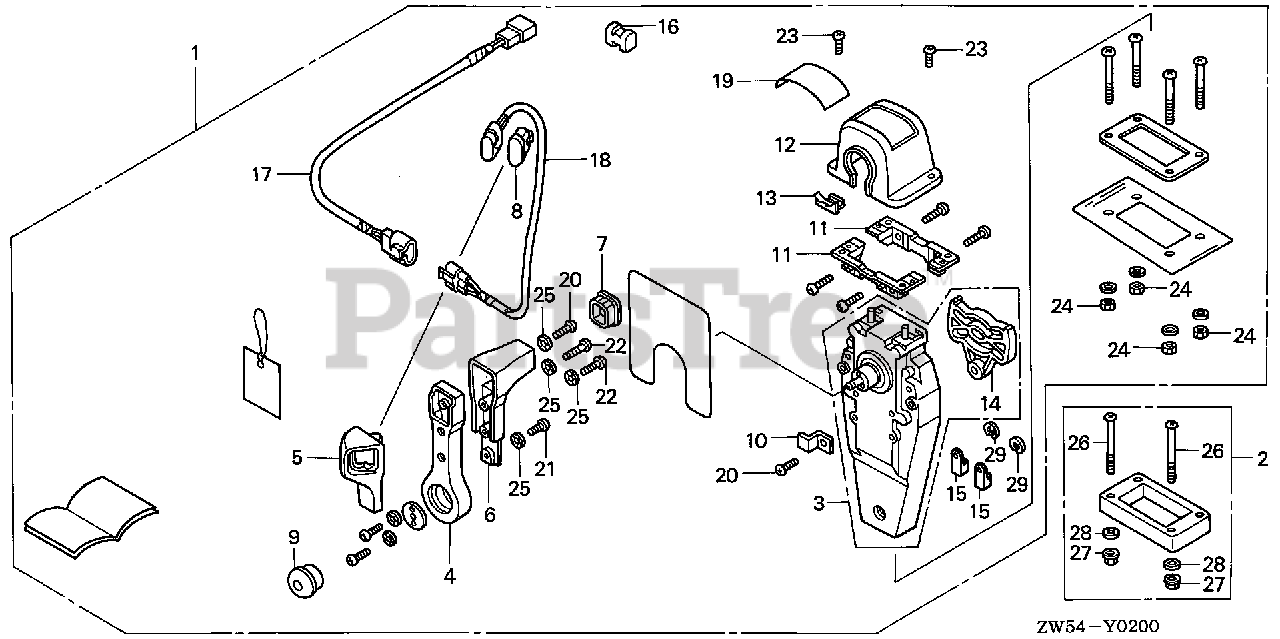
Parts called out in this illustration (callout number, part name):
1	BOX KIT, REMOTE CONTROL
2	SPACER KIT, REMOTE CONTROL BOX
3	HOUSING ASSY., L. (INNER)
4	HANDLE, REMOTE CONTROL
5	COVER, L. GRIP
6	GRIP, REMOTE CONTROL HANDLE
7	CAP, GRIP
8	CAP, SWITCH
9	BUTTON, THROTTLE
10	PLATE, CABLE CLAMP
11	BRACKET, REMOTE CONTROL
12	HOUSING, REMOTE CONTROL BOX
13	HOUSING, LEAD
14	PLATE, DWELL
15	TERMINAL, CABLE
16	SPACER, CABLE CLAMP
17	SUB-HARNESS ASSY., POWER
18	SWITCH ASSY., POWER TRIM-TILT
19	MARK, REMOTE CONTROL (SINGLE)
20	SCREW, PAN (5X16)
21	SCREW, PAN (5X10)
22	SCREW, PAN (5X20)
23	SCREW, PAN (4X10)
24	NUT, HEX. (5MM)
25	WASHER, LOCK (5MM)
26	SCREW, PAN (5X65)
27	NUT, FLANGE (5MM)
28	WASHER, PLAIN (5MM)
29	E-RING (6MM)
